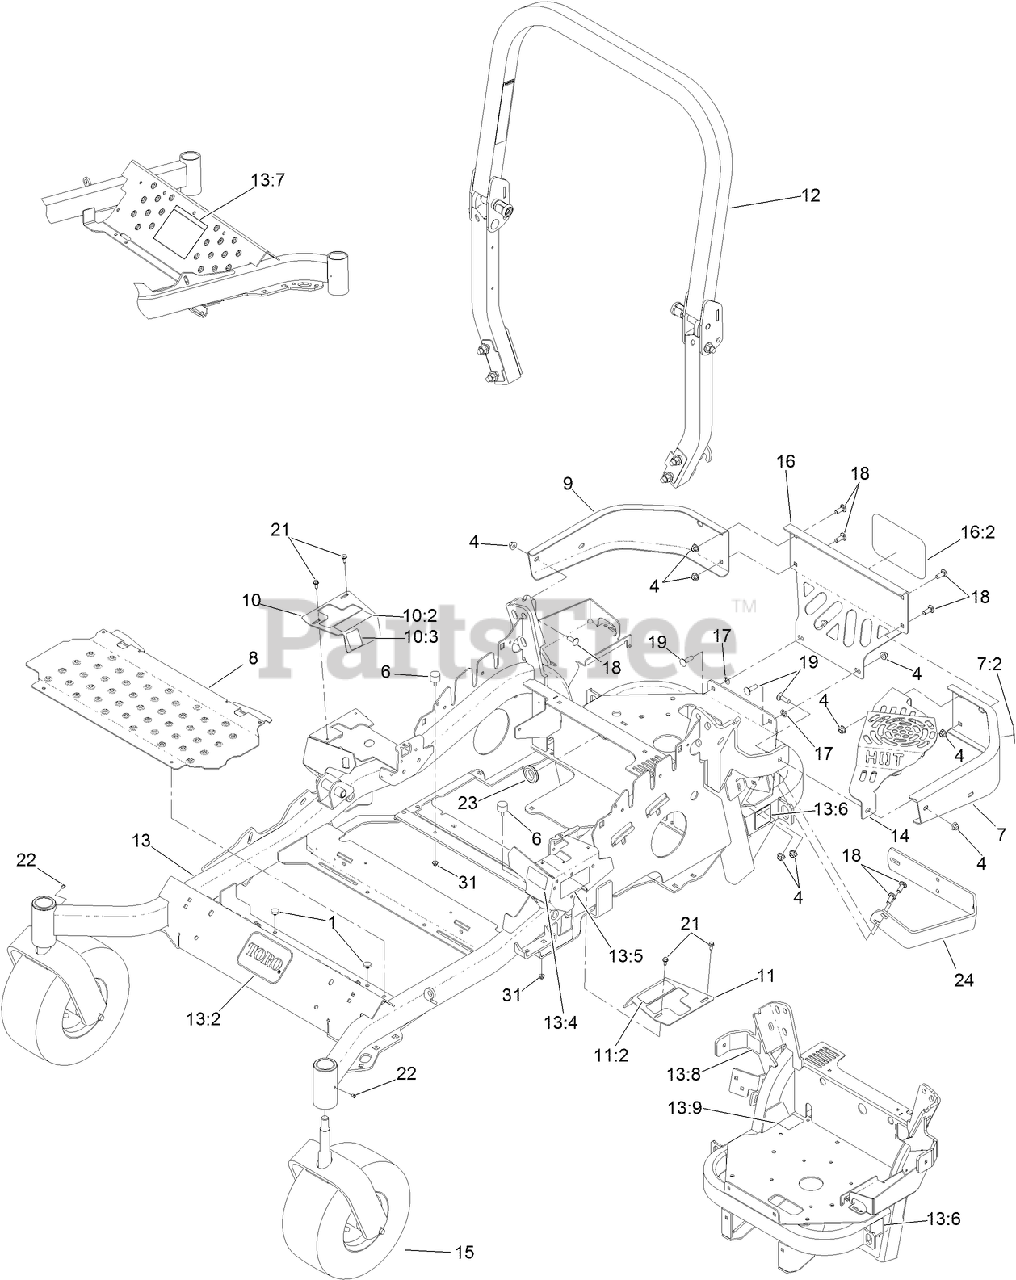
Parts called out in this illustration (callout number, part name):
1	BUMPER
4	NUT-HF, NI
6	BUMPER-RUBBER (W/ STUD)
7	BUMPER-REAR, LH
7:2	DECAL-WARNING
8	FLOORPAN
9	BUMPER-REAR, RH
10	RH MOTION CONTROL COVER ASM
10:2	DECAL-CONTROL, MOTION
10:3	DECAL-PARK BRAKE, CE
11	MOTION CONTROL COVER ASM
11:2	DECAL-CONTROL, MOTION
12	ROPS ASM
13	FRAME ASM
13:2	DECAL
13:4	DECAL-FUEL FILL, CE
13:6	DECAL-HAZARD, PINCHED FINGER
13:7	DECAL-DANGER
13:8	DECAL-SPARK ARRESTER
13:9	DECAL-BYPASS
14	GUARD-MUFFLER
15	Caster Wheel ASM
16	REAR GUARD ASM
16:2	DECAL
17	NUT-PUSH
18	SCREW-CARR
19	BOLT-CARR
21	SCREW-HWH
23	GROMMET
24	GUARD-MUFFLER, SIDE
31	NUT-HF
